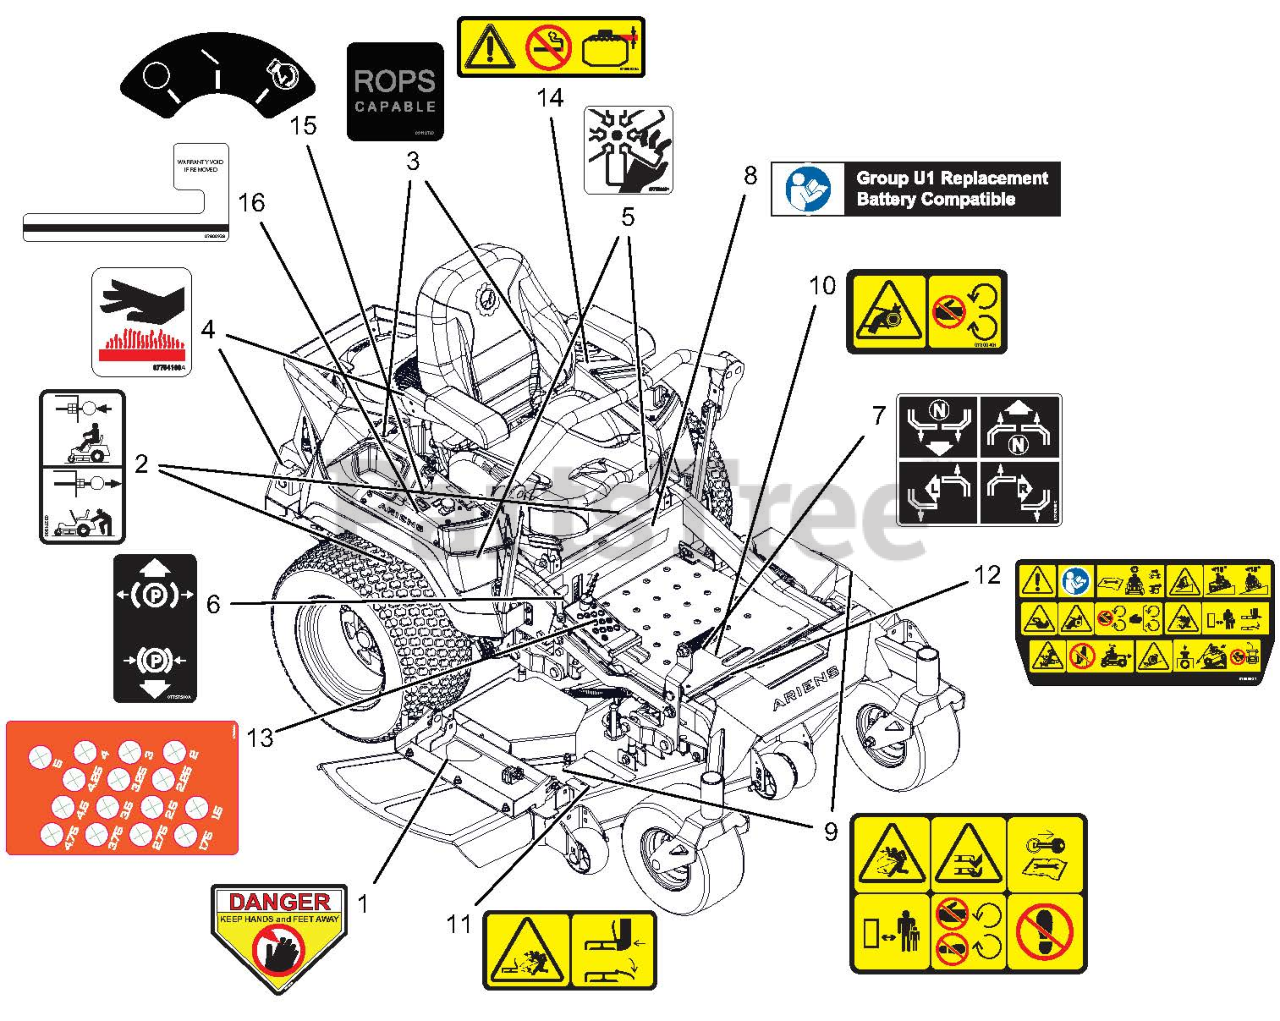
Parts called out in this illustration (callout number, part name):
1	DECAL, DANGER
2	DECAL, TRANSMISSION DISCONNECT
3	DECAL, ROPS LOCATION
4	DECAL, HOT SURFACE
5	DECAL, DANGER FAN
6	DECAL, PARKING BRAKE LEVER
7	DECAL, INSTRUCTIONAL-STEERING
8	DECAL, U1 BATTERY REPLACEMENT
9	DECAL, SAFETY - MOWER DECK
10	DECAL, SAFETY - GUARDING
11	DECAL, SAFETY - DECK GUARDING
12	DECAL, MAIN SAFETY
13	DECAL, ARIENS HOC
14	DECAL, FUEL WARNING
15	DECAL, KEYSWITCH
16	DECAL,HOURMETER - SECURITY
